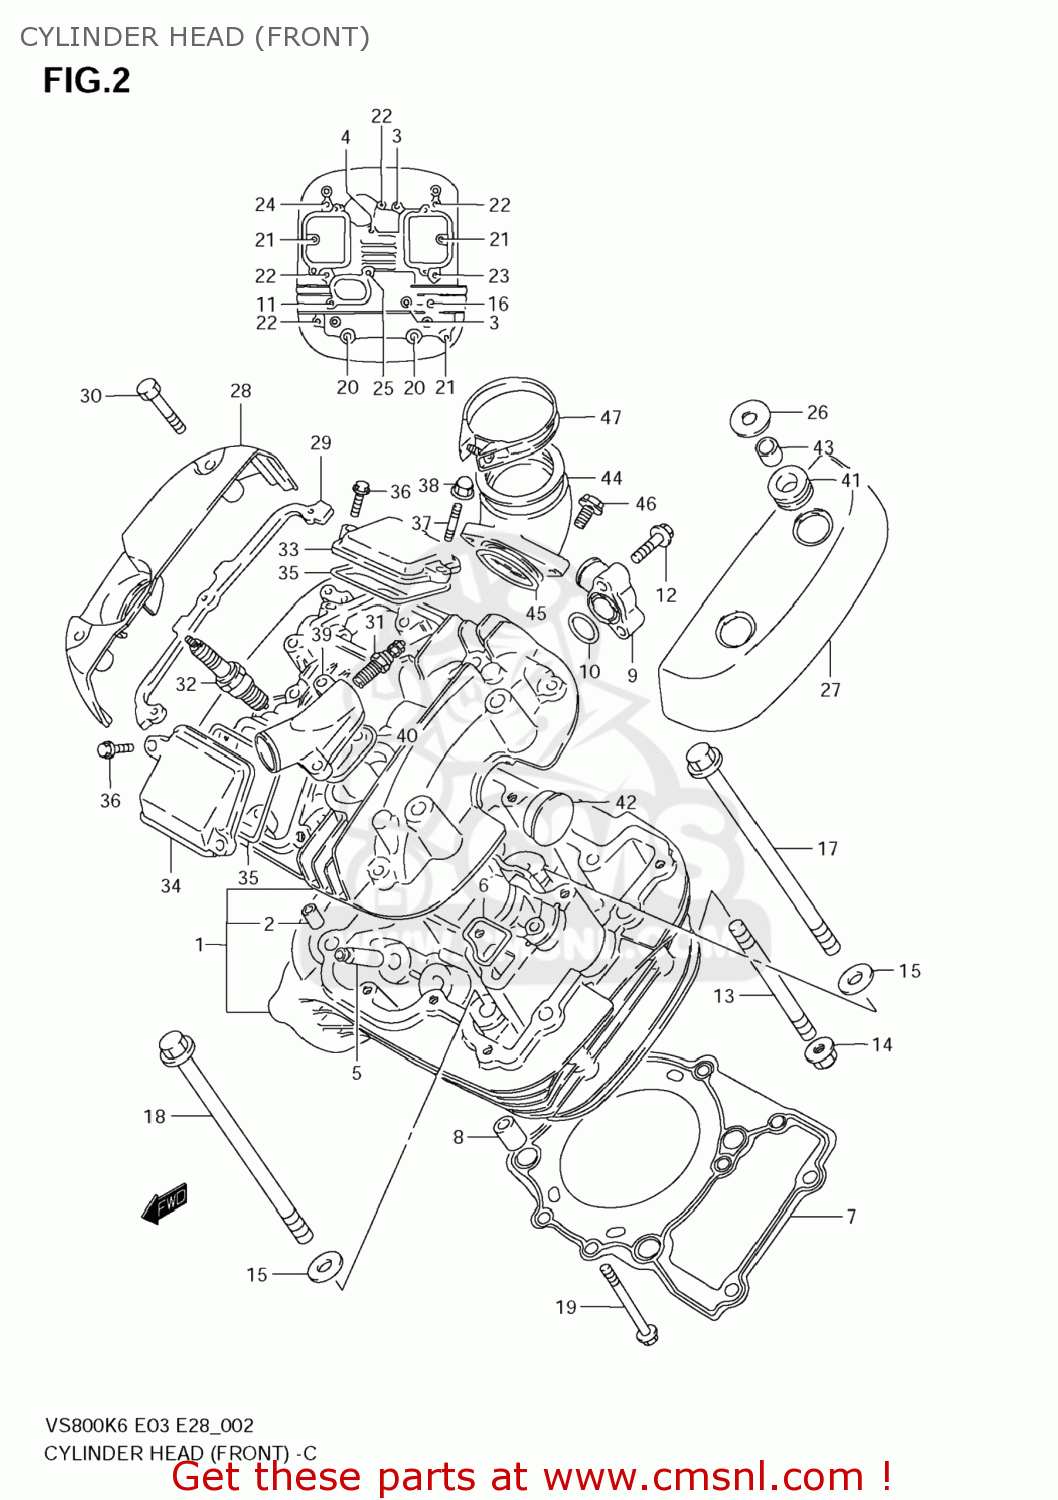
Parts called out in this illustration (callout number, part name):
1	HEAD ASSY,CYLINDER FR
2	PIN(8.4X11X14)
3	BOLT(6X50)
4	BOLT(6X55)
5	GUIDE,VALVE
6	GASKET,CYLINDER HEAD WATER (NAS)
7	GASKET,CYLINDER HEAD FR (NAS)
8	PIN
9	UNION,CYLINDER HEAD WATER
10	O RING(D:2.4,ID:17.8)
11	BOLT
12	BOLT
13	BOLT,STUD
14	NUT
15	WASHER(10.5X22X2.3)
16	BOLT(8X140)
17	BOLT(10X155)
18	BOLT(10X165)
19	BOLT
20	BOLT(8X245)
21	BOLT
22	BOLT
23	BOLT
24	BOLT
25	BOLT(6X55)
26	WASHER(8.5X24X1.6)
27	CAP,CYLINDER HEAD COVER FR,L
28	CAP,CYLINDER HEAD COVER FR,R
29	CUSHION,FR,R CAP
30	BOLT
31	GAUGE ASSY,WATER TEMP
32	SPARK PLUG X22E
33	CAP,INSPECTION INTAKE
34	CAP,INSPECTION EXHAUST
35	GASKET,INSPECTION CAP (NAS)
36	BOLT
37	BOLT,STUD
38	NUT
39	UNION,WATER OUTLET
40	GASKET,WATER OUTLET UNION (NAS)
41	CUSHION
42	PLUG(OD:30)
43	BUSH
44	PIPE ASSY,INTAKE FR
45	O RING(D:2.4,ID:39.7)
46	SCREW
47	CLAMP
